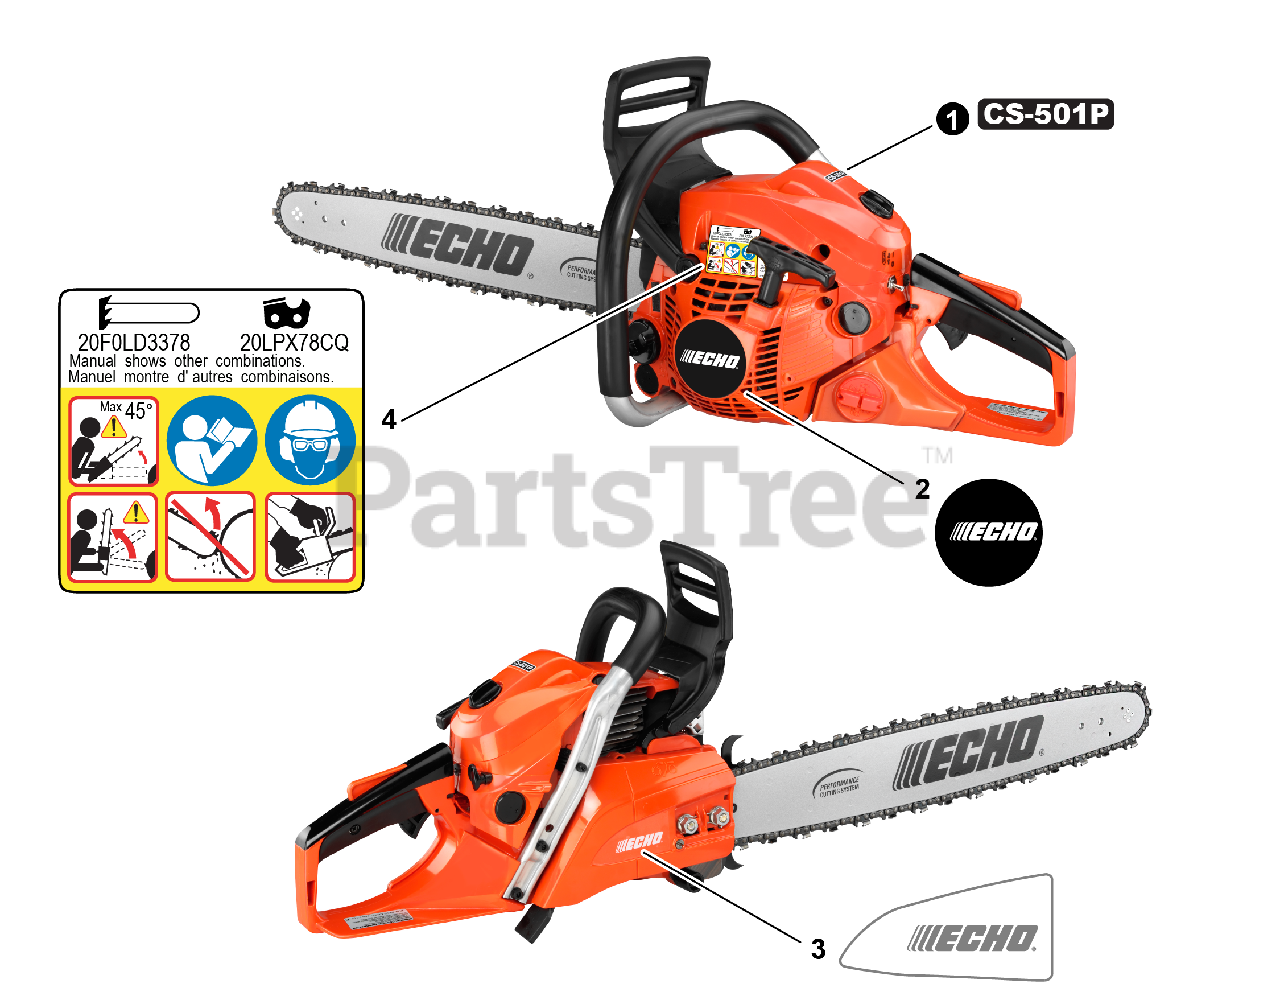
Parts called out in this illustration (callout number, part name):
1	LABEL, CS-501P
2	LABEL, RECOIL STARTER
3	LABEL, ECHO
4	LABEL, CAUTION
